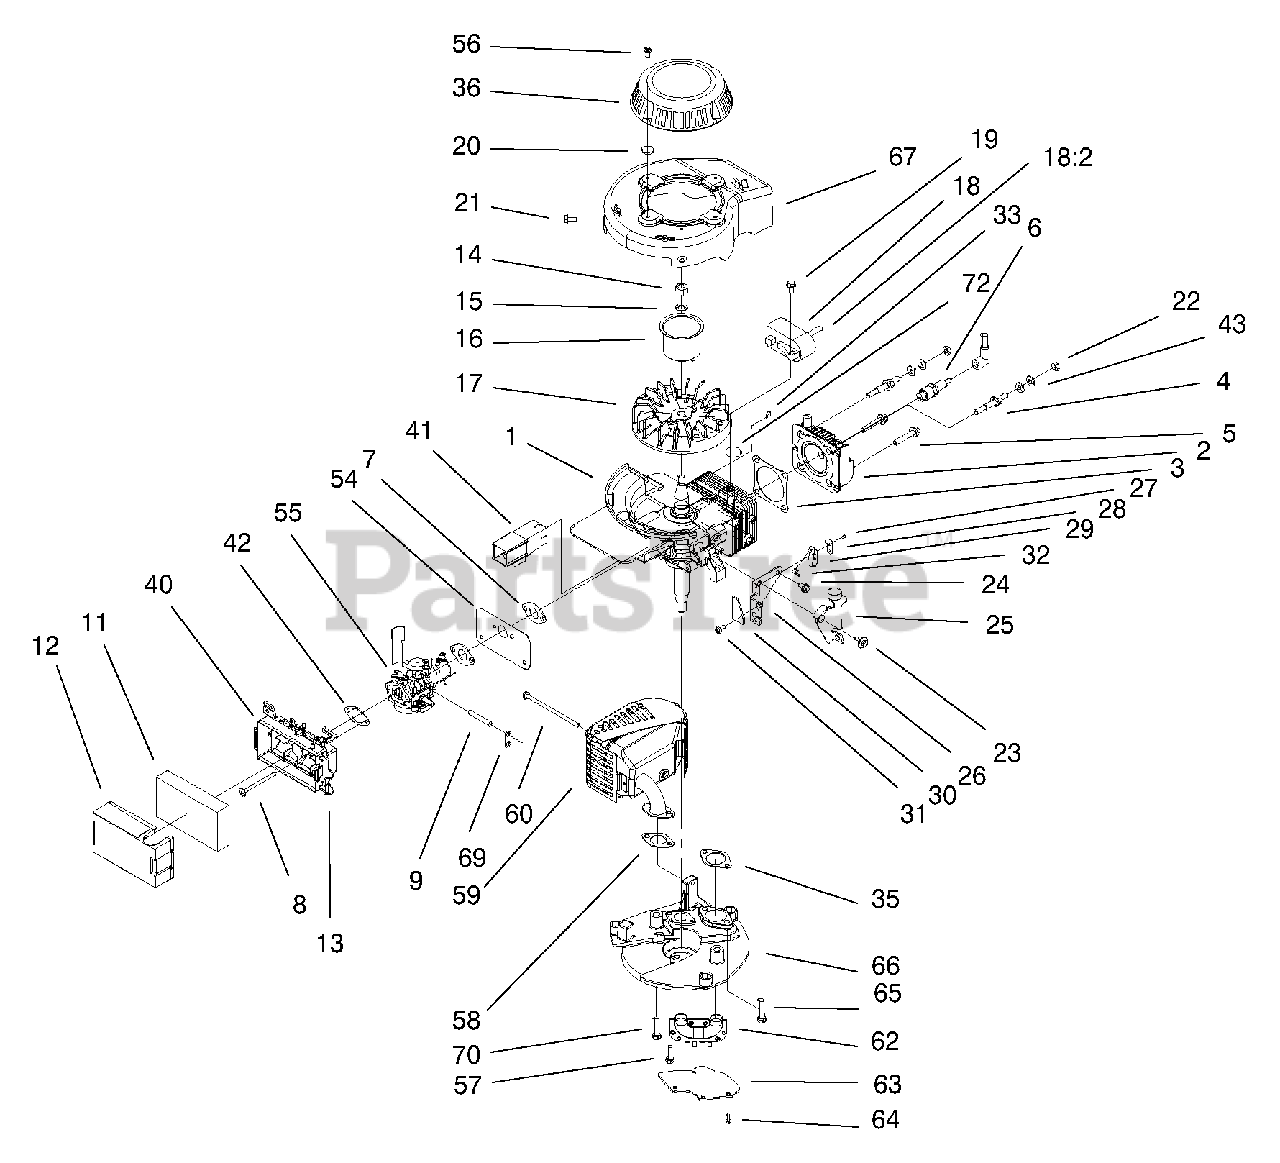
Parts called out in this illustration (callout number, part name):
1	E-S/Block Ser.
2	Head-(Mach)
3	Gasket-Head
5	Bolt-Head
6	Plug-Spark
7	Gasket-Intake
9	Primer Hose
11	Filter-Air
12	Cover-Air Filter
13	Retainer-Fil.
15	Washer-Lock
16	Hub Starter
17	Flywheel-Machined
18	Ignition-Cd
18:2	Ht Lead&cover
18:2	Cover & Term. Ay
19	Screw-Cd Mtg
21	Screw-HH
23	Screw-Shoulder
24	Screw-HWH
25	Brake Plate Ay
26	Plate-Brake Mtg
27	Rivet-Plastic
28	Strap-Insulation
29	Strap-Ground
30	Stop-Gr Strap
31	Screw-Special
32	Wire-Lead
35	Gasket-Exhaust
36	Starter Assy Sm
40	Base Ay-(Air Filter)
42	Gasket-Filter
43	Washer-Belleville
54	Shield-Carb.
55	Carburetor ASM With Gaskets
56	Screw Sems
57	Screw-Cd Mtg
59	Muffler And Guard ASM
60	Bolt-Console
62	Pipe-Transfer
63	Cover-Muffler
64	Screw-HH
65	Screw-HH
66	Mtg. Plate
67	Assembly-Shroud
69	Hose-Retainer
70	Screw H.hd.wash
72	Strap-Tie
